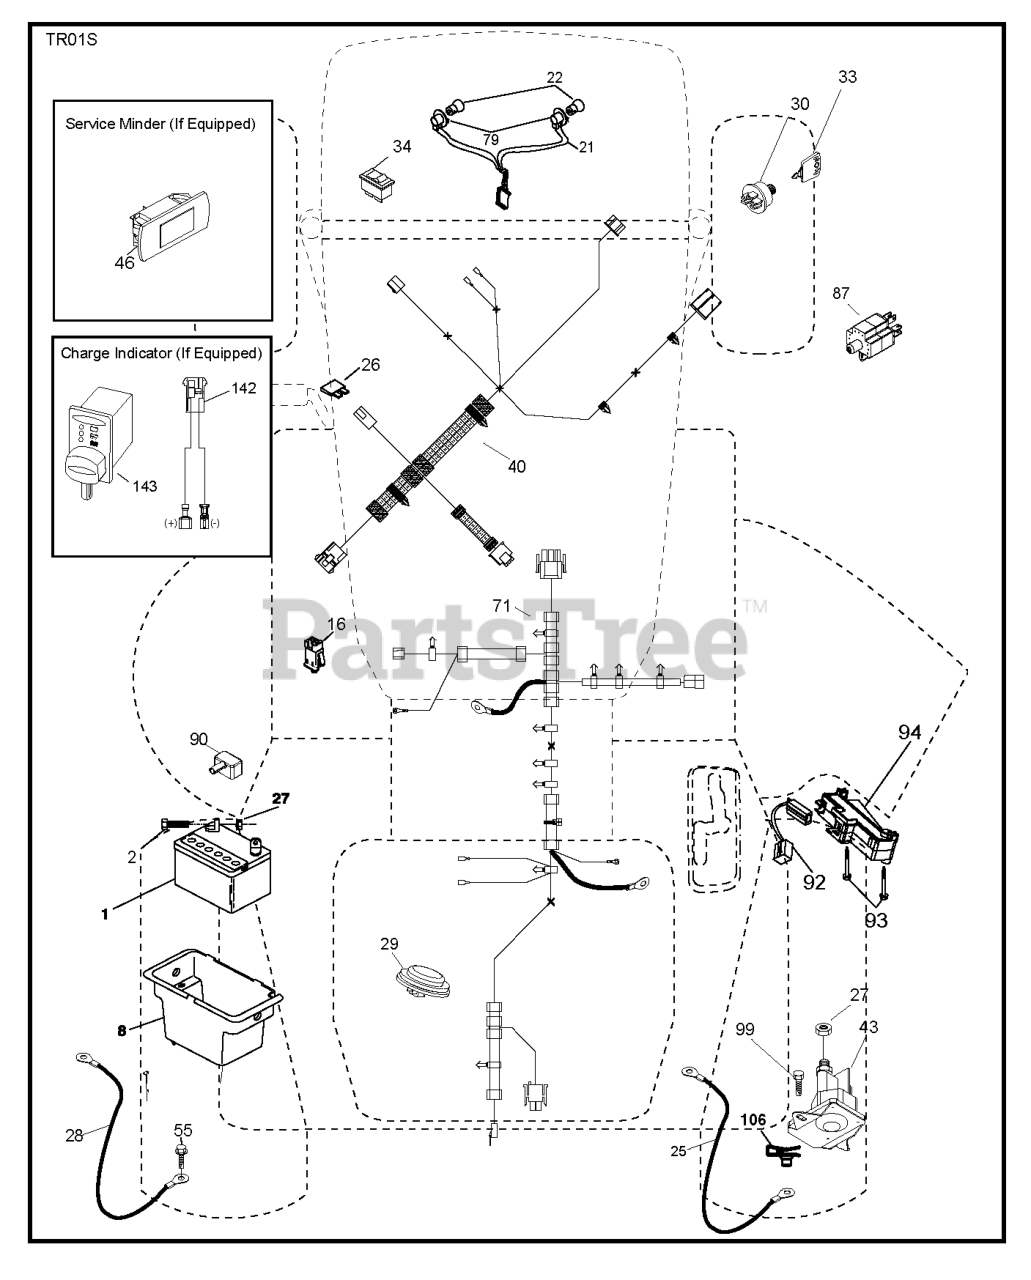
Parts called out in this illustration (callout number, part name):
1	Battery 12 Volt 25 Amp
2	BOLT.HEX.1/4.X.3/4.DICHROMATE
8	BOX.BATTERY.MNT.REAR.L
16	SWITCH INTERLOOK PUSH-IN
21	HARNESS.LIGHT W/4152J BULBS
25	CABLE.BATT.RED.8GA.17
26	FUSE 20AMP
27	NUT
28	CABLE.GROUND.REAR.BATTERY.8G
29	SWITCH.SEAT.DELTA.OPC.
30	SWITCH.IGN.DELTA.W.LGH.ROS
33	KEY.CHAIN.BLISTER.PACK.GEN.USA
40	HARNESS.TEX.DASH.MAN.REAR BATT
43	SOLENOID.STARTER.BRASS.PLUNGER
46	GUAGE.SRVCMNDR.HRMTR.
55	SCREW 5/16"
71	HARNESS.CHASSIS.RRBATT.RDYSTRT
79	BULB HOLDER ASM.
87	SWITCH.INTRLCK.CLUTCH.
90	COVER.TERMINAL.BATTERY
92	HARNESS.PIGTAIL.CONSLE
93	SCREW.PLASTITE
94	MODULE.REVERSE.ROS
99	SCREW HEXWSHR 1/4-20X3/4
106	1/4-20 U NUT
